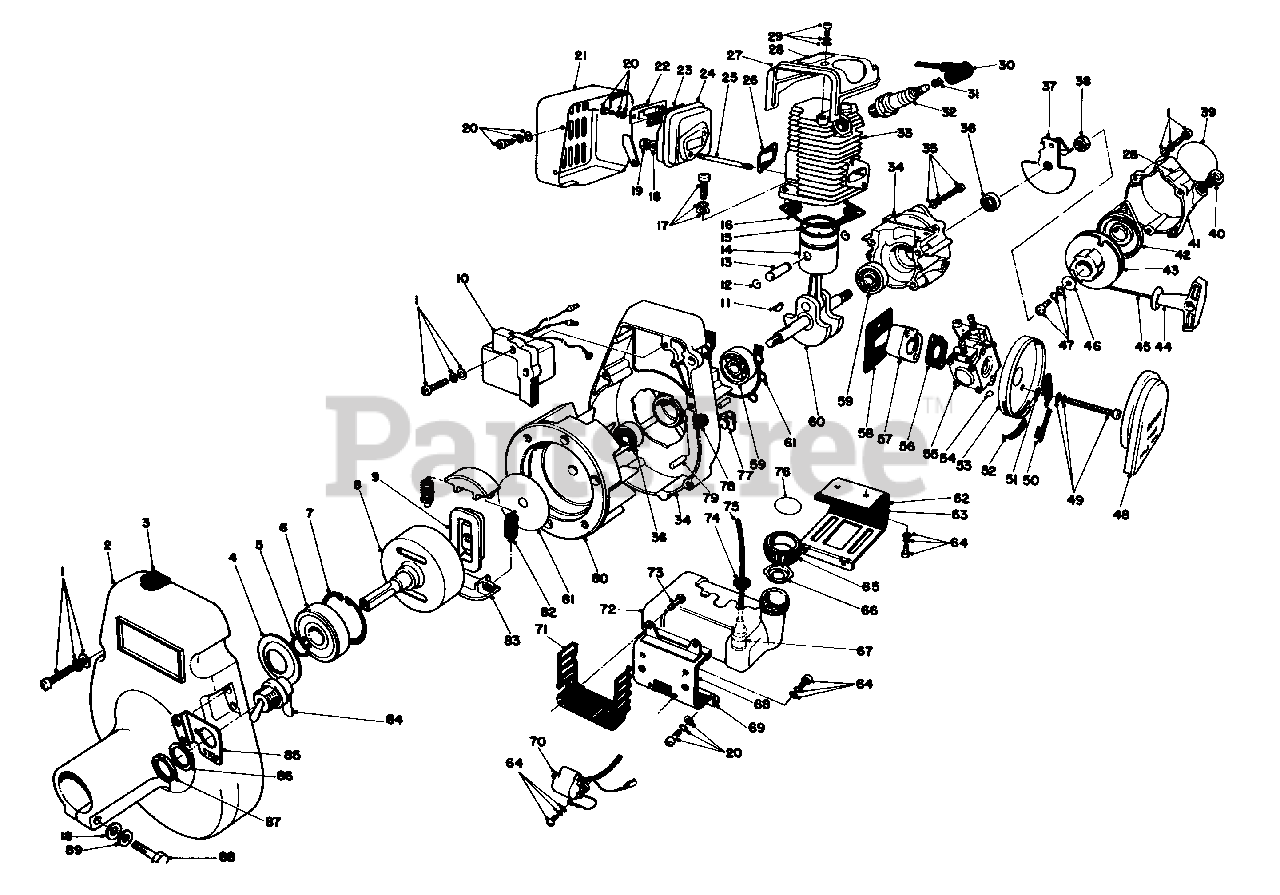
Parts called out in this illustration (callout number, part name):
1	Screw with Washer & Lockwasher
2	Fan Cover
5	Retaining Ring
6	Ball Bearing
7	Retaining Ring
8	Clutch Drum
9	Clutch Boss
10	Ignition Module
11	Woodruff Key
12	Circlip, Piston Pin
13	Piston Pin
15	Piston Ring
16	Gasket, Cylinder Base
17	Screw with Washer & Lockwasher
19	Locknut
20	Screw with Washer & Lockwasher
21	Muffler Cover
22	Lid-Muffler
24	Muffler Body
25	Stud Bolt
26	Gasket, Muffler
27	Cylinder Cover
28	Decal-Hot Surface
29	Screw with Washer & Lockwasher
30	Cap-Spark Plug
31	Coil-Spring-Plug Cap
33	Cylinder
34	Crankcase Set
35	Screw with Washer & Lockwasher
36	Oil Seal
37	Ratchet Assembly
40	Rope Guide
41	Starter Case
42	Rewind Spring
43	Recoil Drum
44	Starter Handle
45	Starter Rope
47	Screw with Lockwasher
48	Air Filter
49	Screw with Washer & Lockwasher
50	Choke Shutter
53	Case-Air Cleaner
54	Clip-Fuel Pipe
55	Carburetor Assembly
56	Gasket
57	Insulator
60	Crankshaft Assembly
61	Gasket-Crankcase
62	Bracket-Fuel Tank
64	Screw with Washer & Lockwasher
65	Cap-Fuel Tank
66	Check Valve
67	Fuel Strainer
69	Bracket-Fuel Tank
70	Ignition Coil
71	Dust Filter
72	Fuel Tank
73	Self Tapping Screw
75	Fuel Pipe
76	Decal Fuel Mix
77	Cord Holder
79	Pin-Knock
80	Flywheel
81	Side Plate
82	Clutch Spring
83	Clutch Shoe
84	Switch (Incl. Ref. #86 & 87)
85	Bracket-Switch
86	Washer
87	Nut
89	Lockwasher
